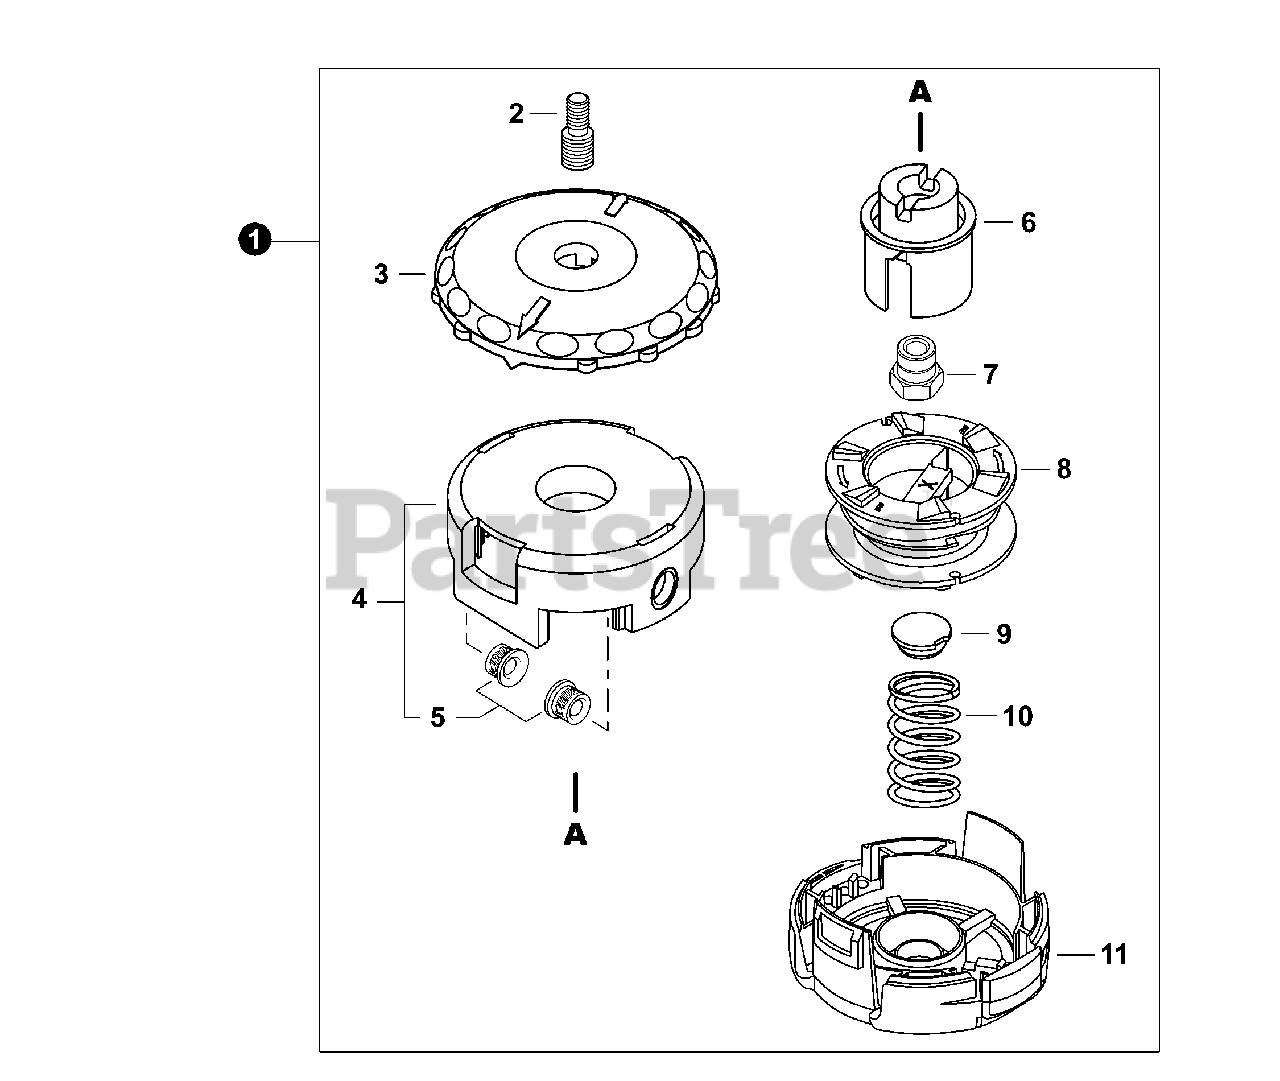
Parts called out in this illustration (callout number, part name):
1	TRIMMER HEAD, SPEED-FEED® 400
2	BOLT, STUD M7×1.00 /M10×1.25 LH GOLD
4	HOUSING ASSY, SPOOL
6	HUB (LH) BLACK
7	BUSHING M10×1.25 LH GOLD
9	CAP, SPRING
10	SPRING, GOLD
11	COVER, SPOOL
